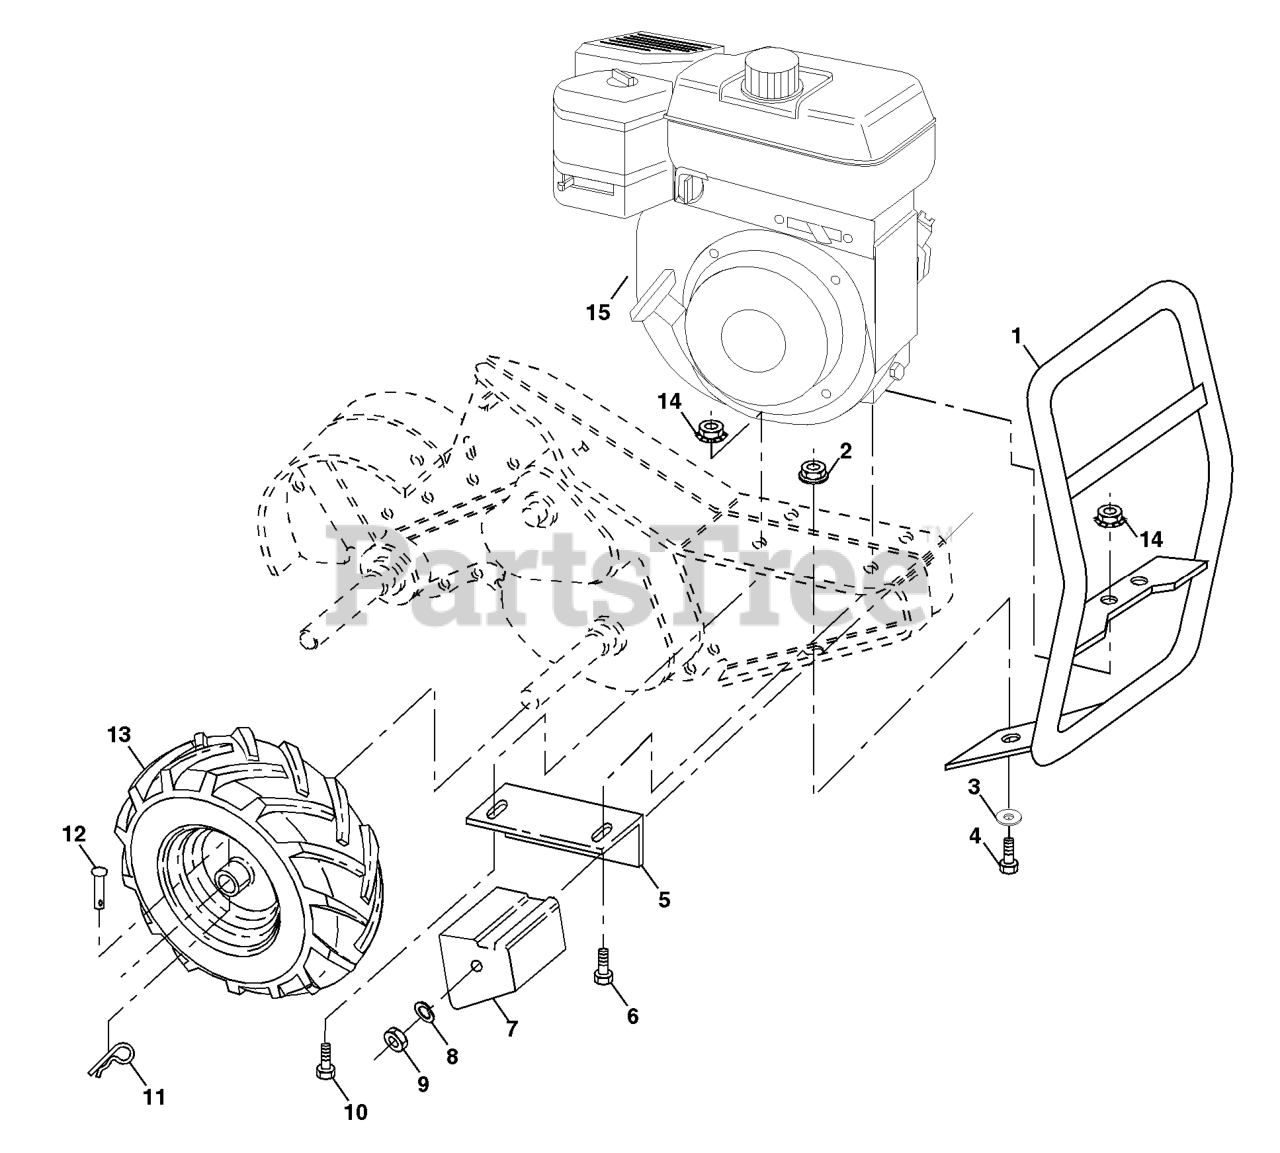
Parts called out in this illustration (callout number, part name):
1	BUMPER
2	LOCKNUT-FLANGE 5/16-18
3	WASHER
4	BOLT
5	DNO BRACKET RH CRT
6	Bolt, Hex 5/16-18 x 2
7	COUNTERWEIGHT, RH
8	WASHER, LOCK 3/8
9	NUT.HEX.3/8-16UNC
10	BOLT
11	RETAINER M
12	RIVET,DRILLED
13	TIRE.16X4-8.CHEVRON.TILLER
13	RIM
13	VALVE STEM LT
14	LOCKNUT-FLANGE 5/16-18
